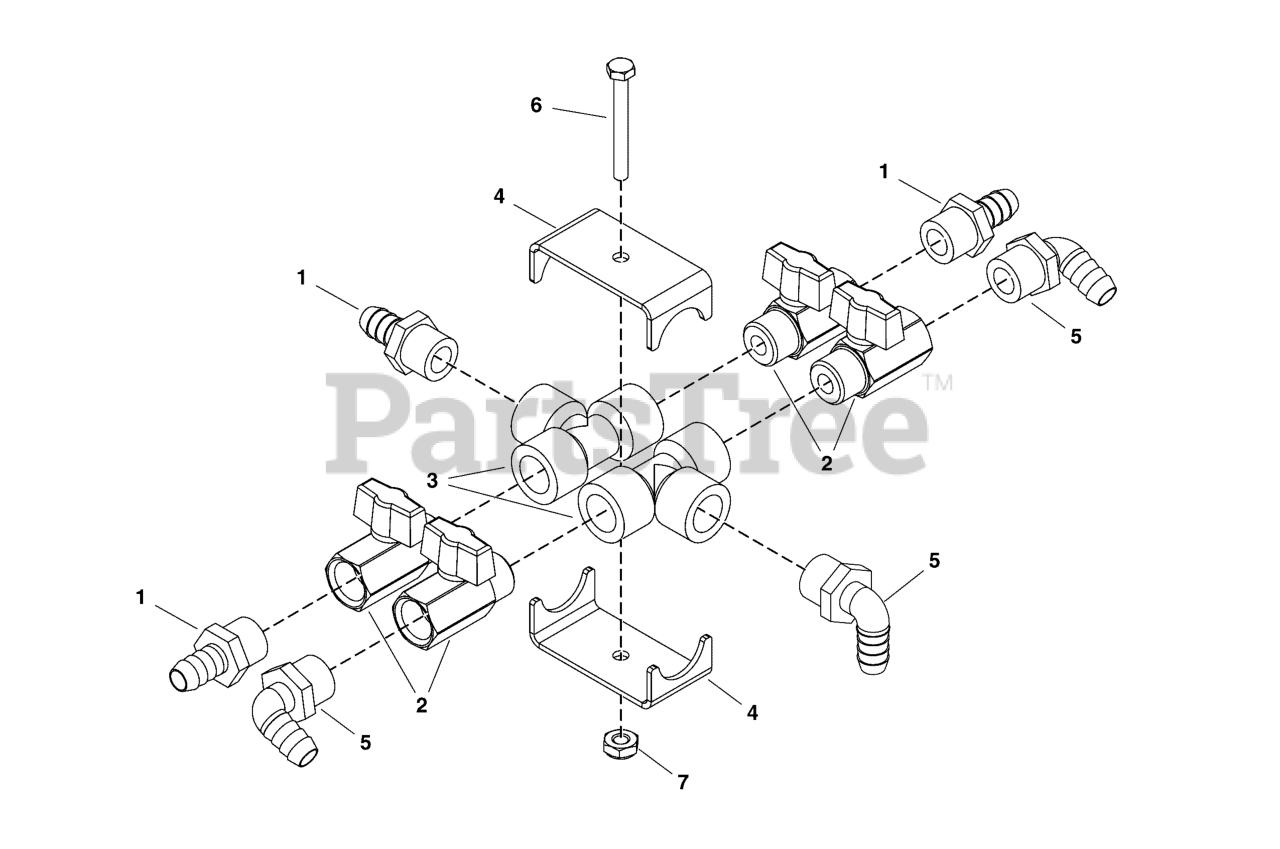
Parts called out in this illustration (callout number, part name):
1	FITTING, 1/2 MPT - 1/2 BARB
2	VALVE, BALL, 1/2 MPT - 1/2 FPT
3	FITTING, TEE, 1/2" FPT
4	PLATE, TIE SPRAY FITTING
5	FITTING, 1/2 MPT - 1/2 BARB, 90 ELBOW
6	SCR-CAP, HEX .250"-20 X 2.250" SS188
7	NUT-HEX-NYLK, .250"-20 TH SS188
